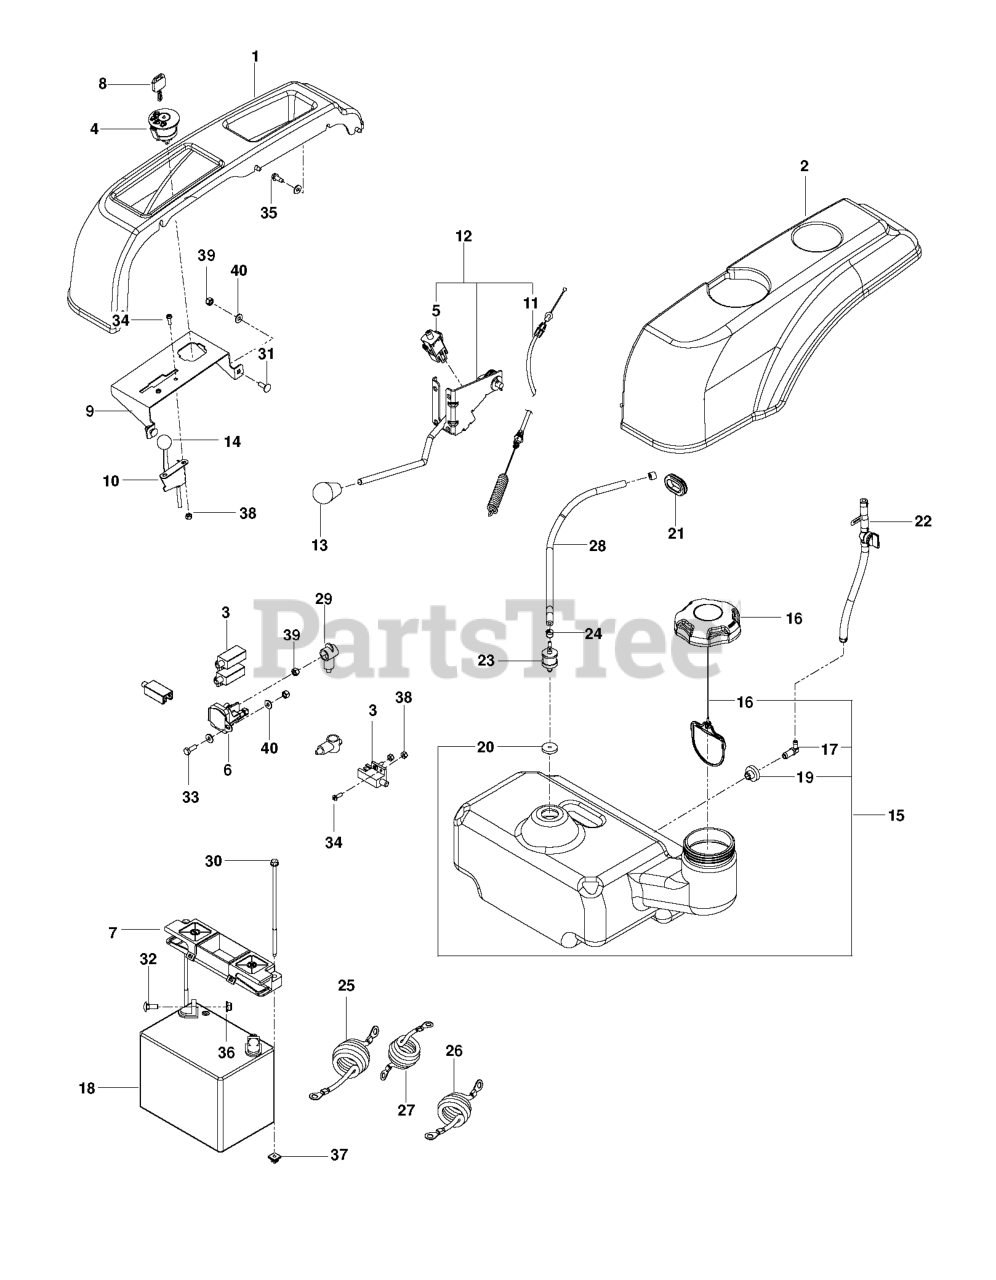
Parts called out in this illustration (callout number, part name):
1	FENDER, RZ 30/38 RT
2	FENDER, RZ 30/38 LT
3	SWITCH INTERLOCKT
4	RP IGNITION SWITCH
5	SWITCH INTERLOCK
7	BATTERY HOLD DOWN
8	KEY MLD GEN DELTA
9	MOUNT, CONTROLS, BLK
10	CABLE, THROTTLE
11	CABLE-CLUTCH ENGAGE
12	CLUTCH.ENGAGE.ASSEM.W/CABLE
13	KNOB - SHIFT
14	KNOB.ROUND.BALL.BLACK
15	FUEL TANK ASM SMALL
16	CAP, FUEL
17	STEM, FUEL TANK
18	BATTERY, 12 V 330 AMP
19	RUBBER GROMMET
20	GROMMET, CHECK VALVE
21	RUBBER GROMMET
23	VALVE.FUEL.CHECK
24	HOSE CLAMP
25	BATTERY CABLE, NEGATIVE
26	POST.CABLE LONG
27	CABLE POSITIVE, LONG
28	HOSE, FUEL, 3/16" X 20"
29	TERMINAL COVER-SM
30	BOLT - 1/4-20 X 7.5
31	RHSNB 1/4C X 3/4
32	BOLT 5/16C X 3/4" CARRIAGE
33	HCS 1/4C X 3/4 HCS
34	SCREW #10-24 X 5/8
35	SCREW 1/4 X 5/8
36	5/16-18 NYLOC FLANGE NUT
37	PUSH NUT-NYLON
38	NUT 10-24 NYLOC
39	NUT.1/4-20.HEX.NYLOC.ZD
40	WASHER 1/4 SAE
